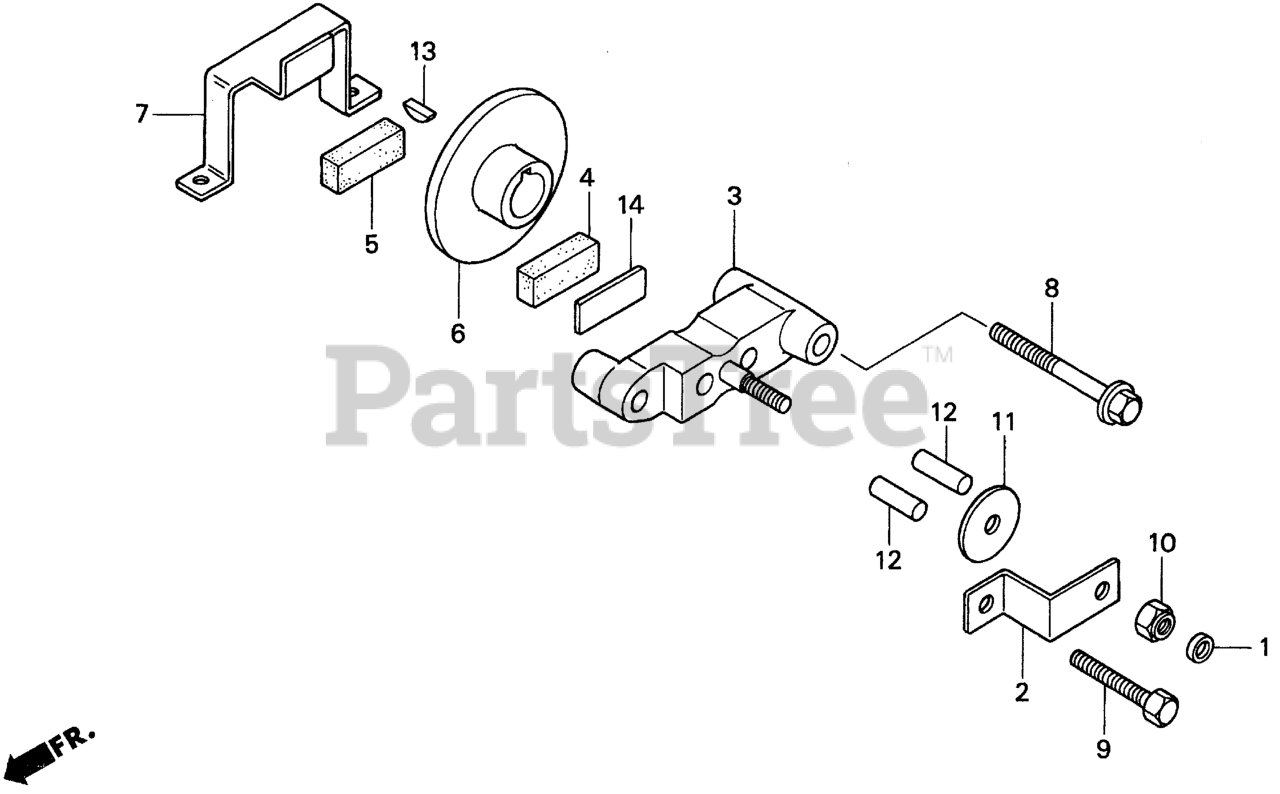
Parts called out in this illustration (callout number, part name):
1	INDICATOR, BRAKE
2	BRACKET, ANTI-ROTATION
3	HOLDER, BRAKE PAD
4	PUCK A, FRICTION
5	PUCK B, FRICTION
6	DISK, BRAKE
7	STOPPER, BRAKE ARM
8	SCREW, TAPPING (5/16)
9	SCREW, TAPPING (5/16X1.44)
10	NUT, LOCK (5/16-24)
11	WASHER, PLAIN (0.32)
12	PIN, DOWEL
13	KEY, WOODRUFF
